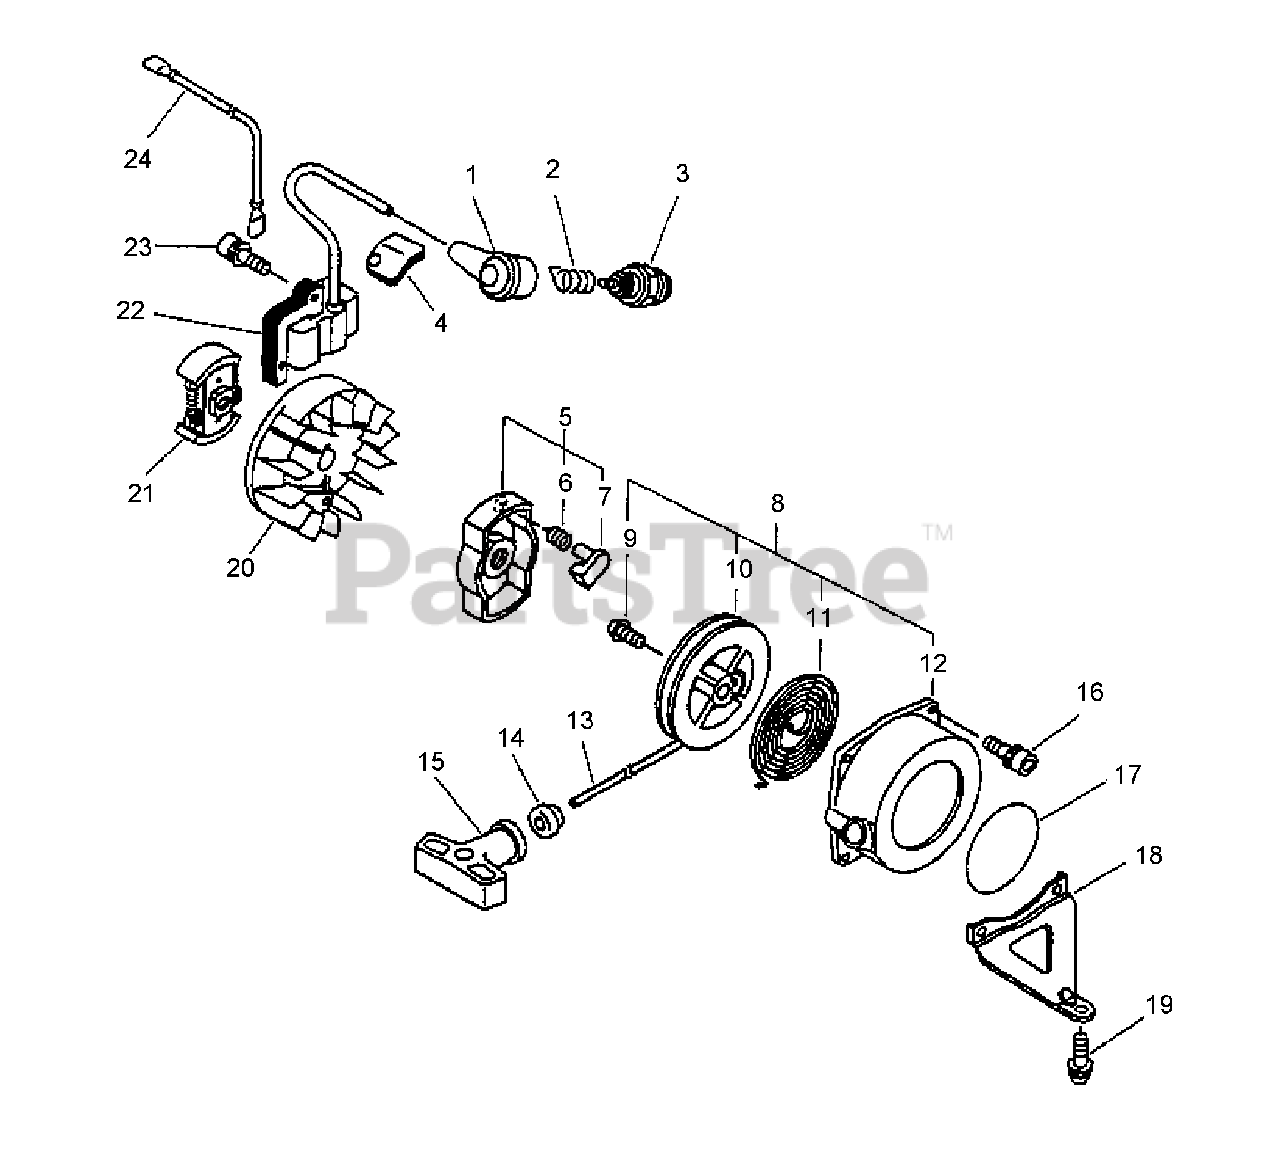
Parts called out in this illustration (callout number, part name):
1	CAP, SPARK PLUG
2	TERMINAL, SPARK PLUG CAP
3	SPARK PLUG -- BPM-7Y
4	COVER, DUST
5	STARTER PAWL ASSY
6	SPRING, RETURN
7	PAWL, STARTER - BLACK
8	STARTER ASSY
10	REEL, ROPE
11	ROPE, STARTER - 3X990
12	GUIDE, ROPE
13	GRIP, STARTER
14	SPRING, REWIND
15	CASE, STARTER
16	SCREW - 4X16
17	LABEL - ECHO
18	SUPPORT, REAR HANDLE
19	SCREW - 5X16
20	FLYWHEEL
21	CLUTCH ASSY
22	COIL, IGNITION
23	SCREW - 4X22
24	LEAD - IGNITION
